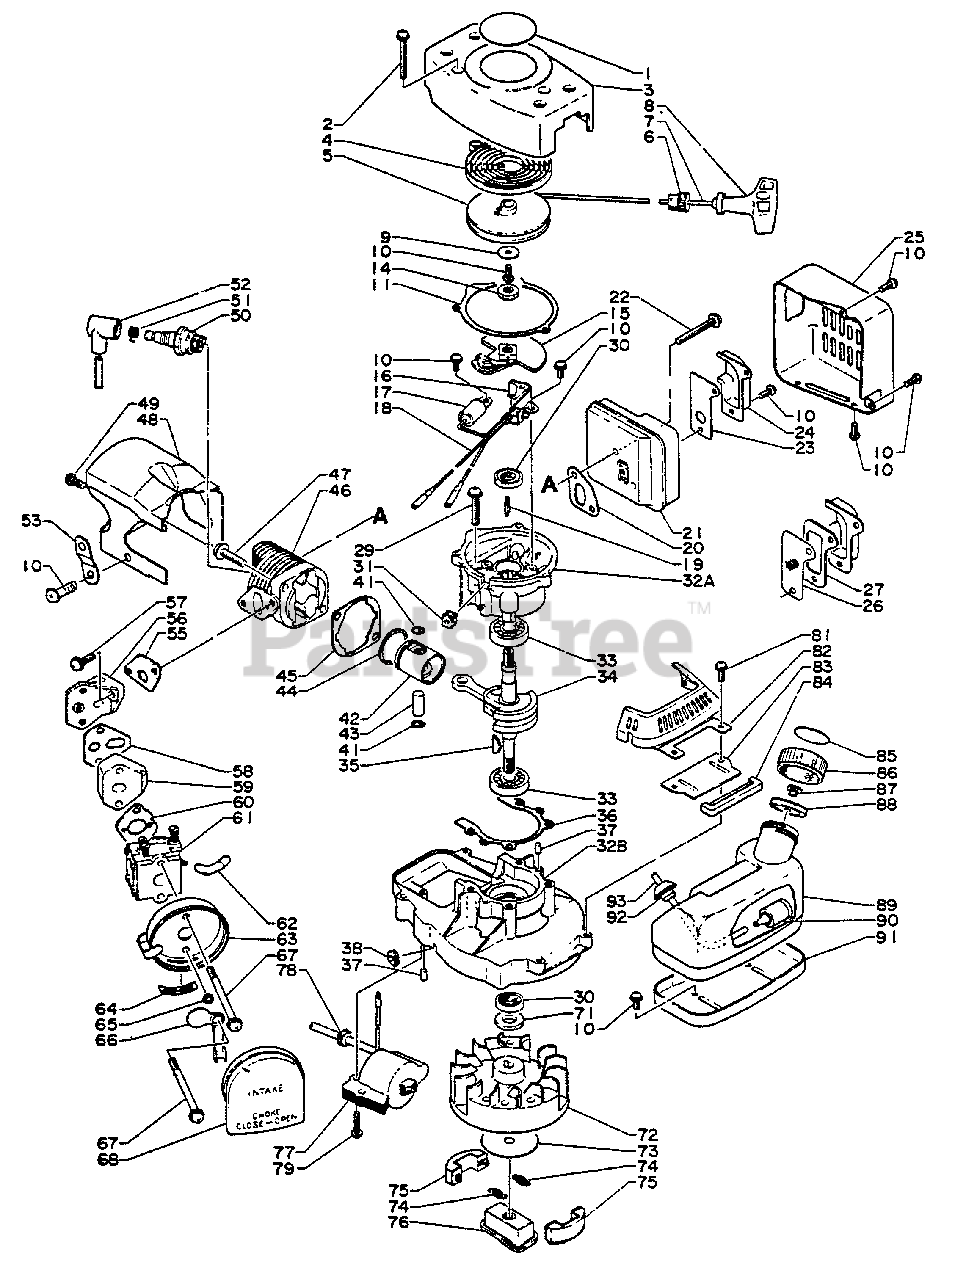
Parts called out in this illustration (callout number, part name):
1	LABEL - ECHO
2	SCREW - 4X40
3	CASE, STARTER
4	SPRING, REWIND
5	REEL, ROPE
6	GUIDE, ROPE
7	ROPE, STARTER - 3X850
8	GRIP, STARTER
10	SCREW - 4X10
11	GASKET, STARTER
15	STARTER PAWL ASSY
16	CONTACT POINT SET
17	CONDENSER
18	LEAD - GROUND
19	PAD, OIL
20	GASKET, EXHAUST
21	CASE, MUFFLER
22	SCREW - 5X40
23	GUIDE, EXHAUST
24	GUIDE, EXHAUST
25	COVER, EXHAUST
26	SCREEN, SPARK ARRESTOR
27	RETAINER, SCREEN
29	SCREW - 5X30
30	SEAL, OIL
32	CRANKCASE KIT
33	BEARING, BALL - 6200
34	CRANKSHAFT ASSY
36	GASKET, CRANKCASE
37	PIN - LOCATING
41	RING, RETAINING
42	PISTON
43	PIN, PISTON
44	RING, PISTON
45	GASKET, CYLINDER
46	CYLINDER
47	SCREW - 6X22
48	COVER, ENGINE
49	SCREW - 5X10
50	SPARK PLUG -- BM-6A
51	TERMINAL, SPARK PLUG CAP
52	CAP, SPARK PLUG
53	BRACKET
55	GASKET, INTAKE
56	BASE, INSULATOR
57	SCREW - 5X16
58	GASKET, INTAKE
59	INSULATOR, INTAKE
60	GASKET, INTAKE
61	CARBURETOR WA-89
62	PIPE
63	CASE, AIR FILTER
65	WASHER - 5
66	SHUTTER, CHOKE
67	SCREW - 5X57
68	FILTER, AIR
72	FLYWHEEL
73	PLATE, CLUTCH
74	SPRING, CLUTCH
75	SHOE, CLUTCH
76	HUB, CLUTCH
77	COIL, IGNITION
79	SCREW - 4X20
81	SCREW - 4X12
83	BRACKET, FUEL TANK
84	CUSHION
85	LABEL - FUEL MIX
86	CAP
88	HOLDER, VENT
89	TANK, FUEL
90	FILTER, FUEL
91	BRACKET, FUEL TANK
93	FUEL PIPE KIT
